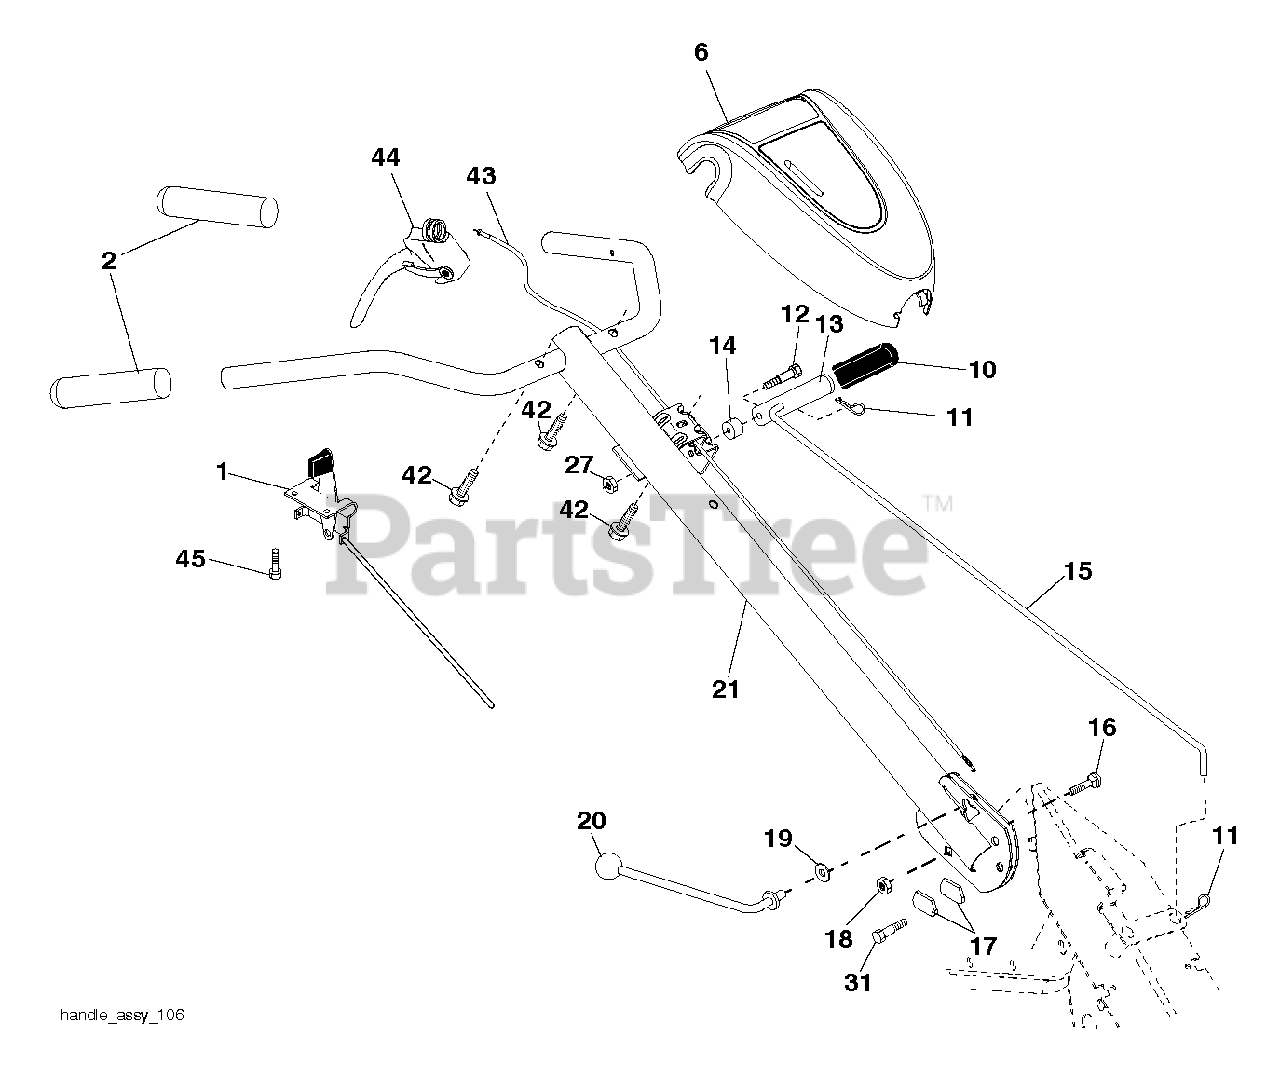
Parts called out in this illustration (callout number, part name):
1	CONTROL.THROTTLE
2	GRIP.1X5.06
6	CONSOLE.GREY.W/THROT.TR430
10	GRIP T
11	RETAINER M
12	SHOULDER BOLT ST
13	HANDLE.SHIFT.TILLER
14	GROMMET.RUBBER.CRT.TILLER
15	SHIFT ROD CRT
16	BOLT D
17	LOCK.HANDLE.CRT
19	WASHER CRT
20	LEVER.LOCK.CRT
21	HANDLE.ASM.HUSQ/P.PRO.GREY
27	NUT T
31	BOLT.PIVOT
42	SCREW.#10 X 0.750.BOS
43	CABLE.HANDLE.TINE.CONTROL.CE
44	CONTROL.HANDLE.TWO.FUNCTION.CE
45	SCREW.#10 X 0.500
